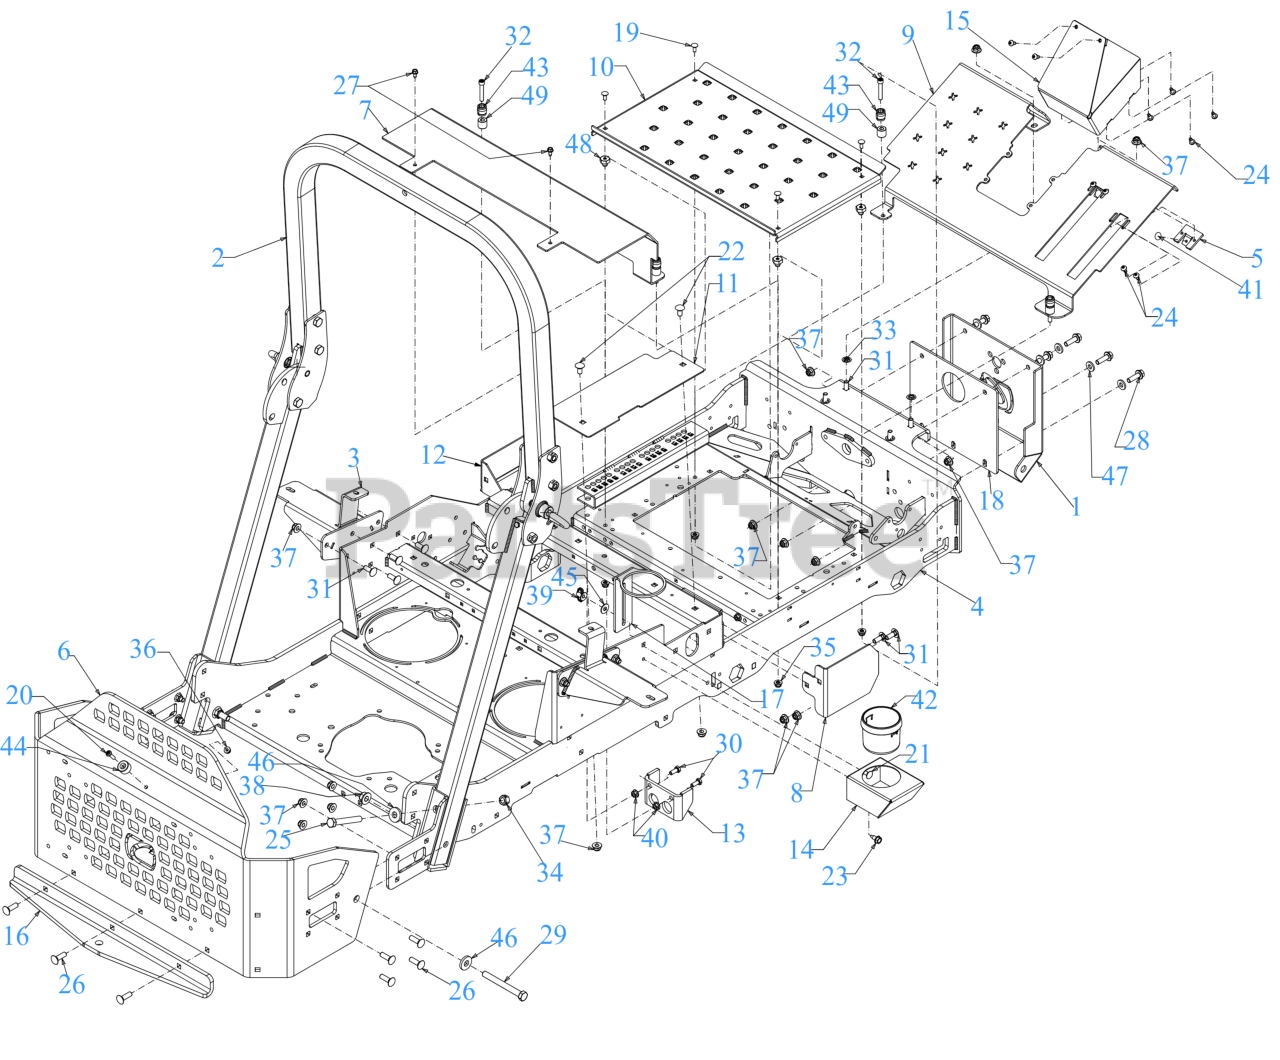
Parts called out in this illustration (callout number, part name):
2	PRO Z ROPS KIT
3	FUEL TANK MOUNT
4	FRAME ASSEMBLY
5	REVERSE PEDAL STOP BRACKET
12	SEAT BOX END COVER (LH)
18	FRONT MOUNTING PLATE SPACER
19	CARRIAGE BOLT 1/4-20 x .62
20	MACHINE SCREW 1/4-20:1
21	CARRIAGE BOLT 5/16-18 x 1.00
22	CARRIAGE BOLT 3/8-16 x .750 GR5
23	SCREW 5/16-18 x .750
24	SCREW 1/4-20 x .5
25	SCREW 1/2-20 x 3.50 GR5
26	CARRIAGE BOLT 3/8-16 X1.25 GR5
27	SCREW 1/4-20 X.500
28	SCREW 3/8-16 x 1.25 GR5
29	SCREW 1/2-13 x 4.5 GR 5
30	SCREW 5/16-18 x .75 GR5
31	CARRIAGE BOLT 3/8-16 x 1.00 GR5
32	SCREW 5/16-18X1.75 GR5
35	FLANGE LOCK NUT 5/16-18
36	FLANGE LOCK NUT
39	WING NUT 5/16-18
40	FLANGE NUT
41	RATCHET CLIP
43	RADIAL BUMPER
45	FLAT WASHER
46	FLAT WASHER .531 x 1.25 x .181
47	FLAT WASHER
48	SHOULDER SPACER
